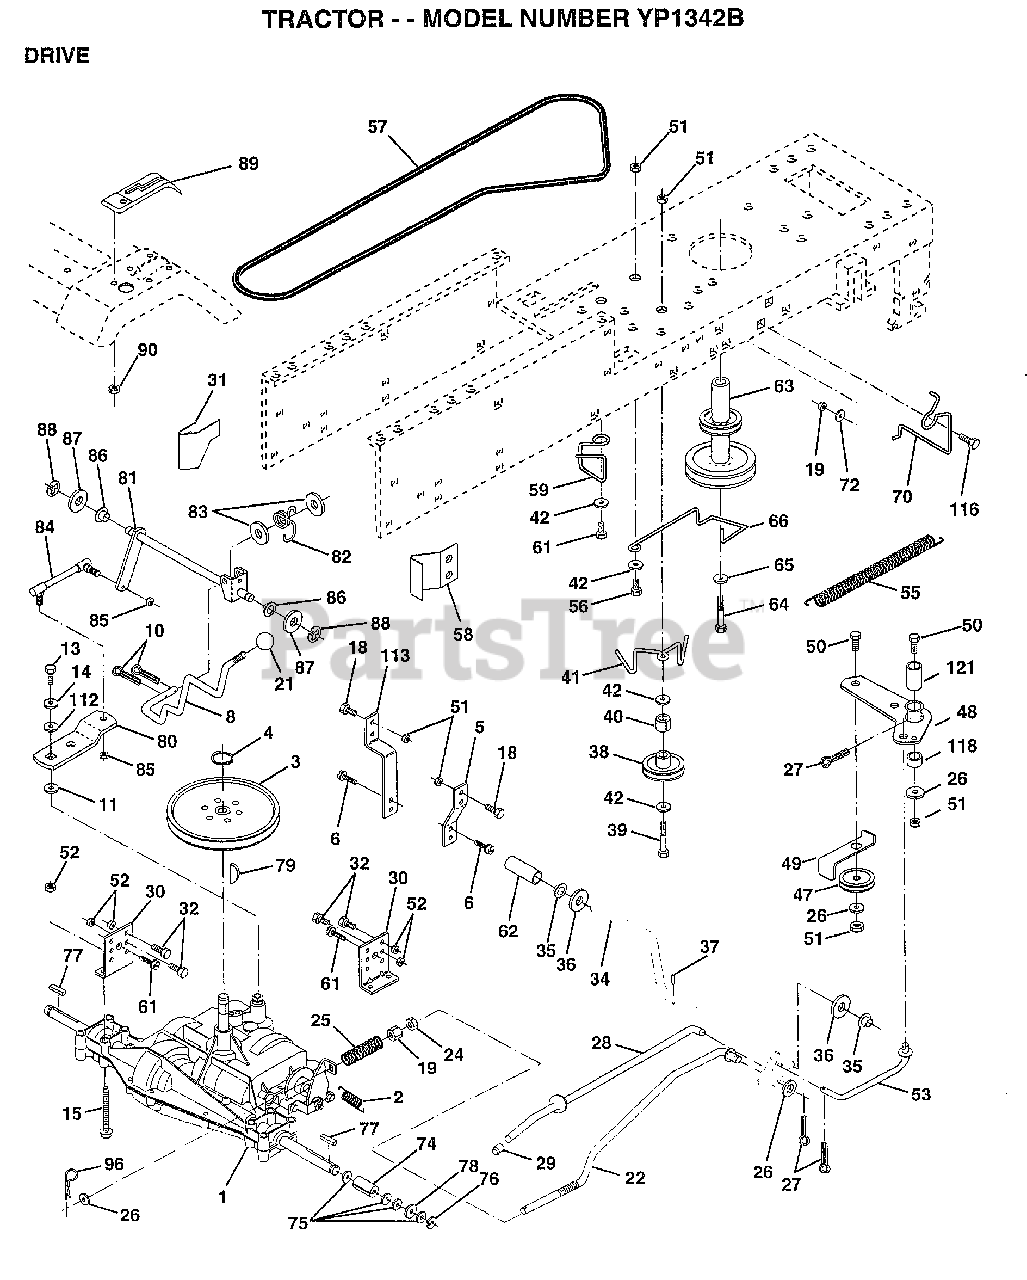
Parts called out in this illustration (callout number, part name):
2	SPRING.BRAKE.RETU
3	PULLEY TRANS
5	STRAP TORQUE
6	SCREW
8	ROD SHIFT FEND LT
10	PIN COTTER 1/8
11	WASH-SHFT PLT LT
13	BOLT.1/4-28.W/PAT
14	LOCKWASHER
15	BOLT.HX.FLG.5/16
18	BOLT
19	NUT
21	KNOB.DUCKHEAD.1/2
22	BRAKE ROD
24	NUT
25	SPRING ROD LT
26	WASHER
27	COTTER PIN
28	ROD.BRAKE.PARK.LT
29	PLUNGER CAP T
30	TRANSAXLE MTG BKT
31	"KEEPER,BELT LH T"
32	BOLT
34	SHAFT ASM-PEDAL F
35	NYLON BEARING
36	WASHER LT
38	PULLEY.IDLER.FLAT
39	BOLT
40	SPACER T
42	WASHER
48	BELLCRANK ASM
49	RETAIN BELT
53	"LINK, CLUTCH T"
55	"SPRING, RETURN LT"
58	"KEEPER,BELT RH T"
59	KEEPER BELT CNTSP
61	SCREW
62	PEDAL COVER T
63	PULLEY.ENGINE
64	BOLT
65	LOCKWASHER
66	KEEPER-BELT
70	KEEPER BELT ENG
72	WASHER
74	SPACER AXLE
75	WASHER
76	E-RING LT
77	SQUARE KEY
78	WASHER
80	"ROD,LINK SHIFT"
81	SHAFT.CROS.18.STR
82	"SPRING,TORSION"
83	WASHER
84	"ROD,TIE "
85	NUT.CNT.LOCK.1/4
86	BUSHING
87	WASHER D
88	KLIP RING
90	NUT
96	RETAINER M
112	WASHER LT
113	"STRAP,TORQUE"
116	BOLT RDHD 3/8-16
118	SPACER-BELLCRANK
121	NYLINER-CLUTCHING
